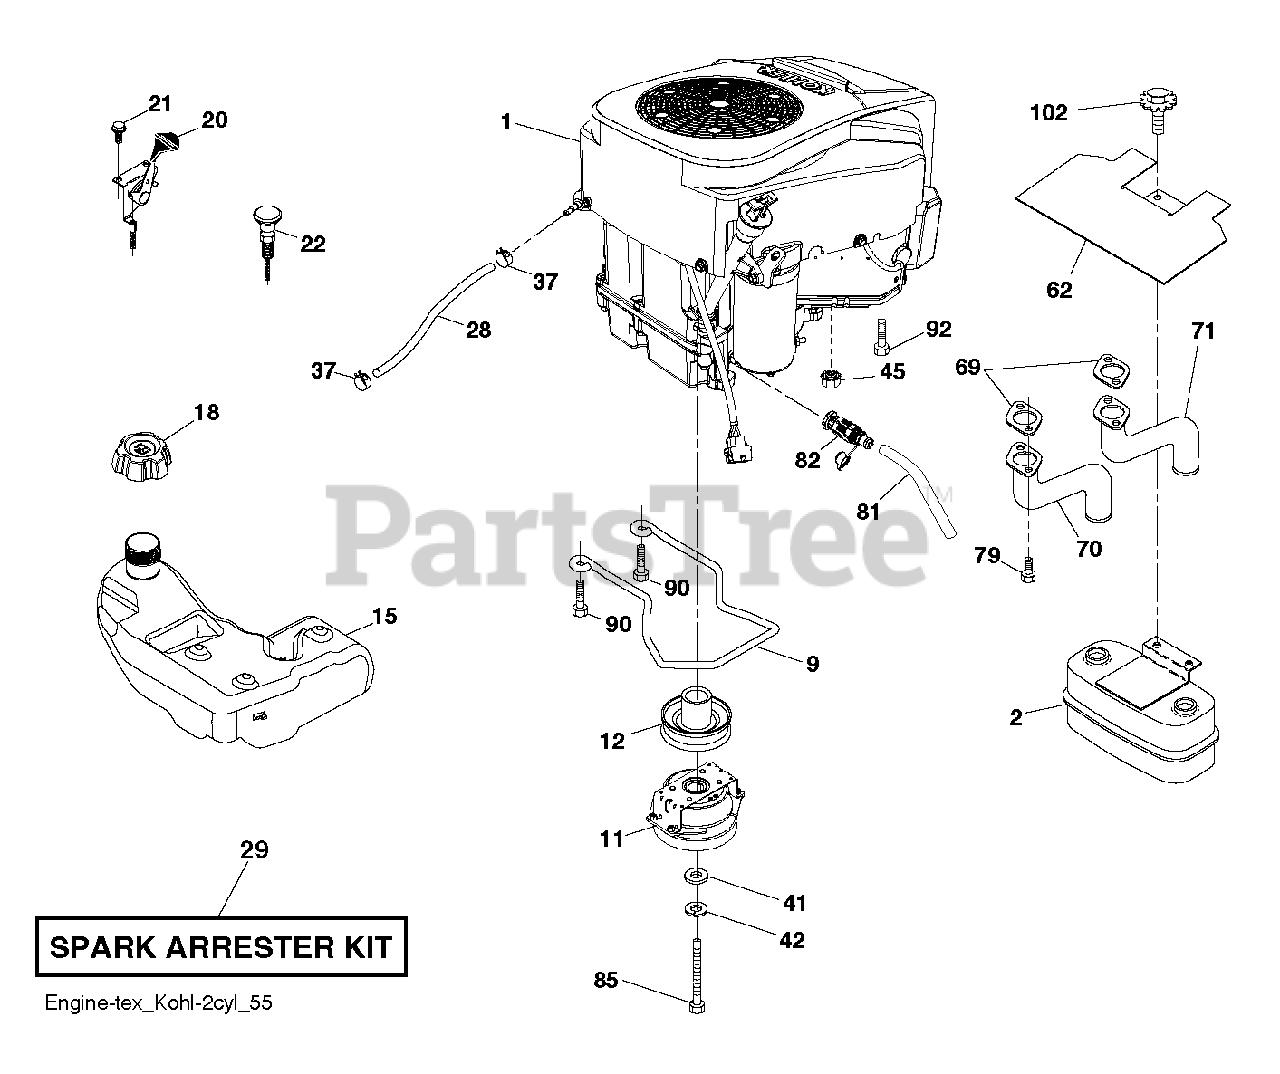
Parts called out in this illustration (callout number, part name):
2	Muffler Assembly, Twin MN
9	KEEPER.BELT.ENG.4.25"2.BLT.431
11	CLUTCH.OGURA.5.0PD.GT1.5A-EH07
12	PULLEY.ENGINE.TUFFTORQ
15	Tank Assembly, 3Gal EPA
18	CAP ASSY FUEL 3" GRAY
20	THROTTLE CONTROL
21	SCREW.#10 X 0.750.BOS
22	CONTROL.CHOKE.ERGO.PUSH-IN.BLA
28	LINE.FUEL.64"REAR.EMIS
29	KIT.SPARK ARRESTOR 794945 B&S
37	HOSE CLAMP
42	WASHER 7/16 LOCK
45	NUT
62	SHIELD.HEAT.MUFFLER
69	GASKET.EXHAUST.KOHL.CV18-CV26
70	PIPE.EXHAUST.LH.CV18/20
71	PIPE.EXHAUST.RH.CV18/20
79	SCREW.SOCKET HD.5/16-1
81	TUBE, DRAIN OIL ASM.
82	VALUE.OIL.DRAIN
85	BOLT.HEX.7/16-20X3.75.GR5.RED
90	SCREW 3/8-16X1
92	SCREW 3/8-16X1
102	SCREW
